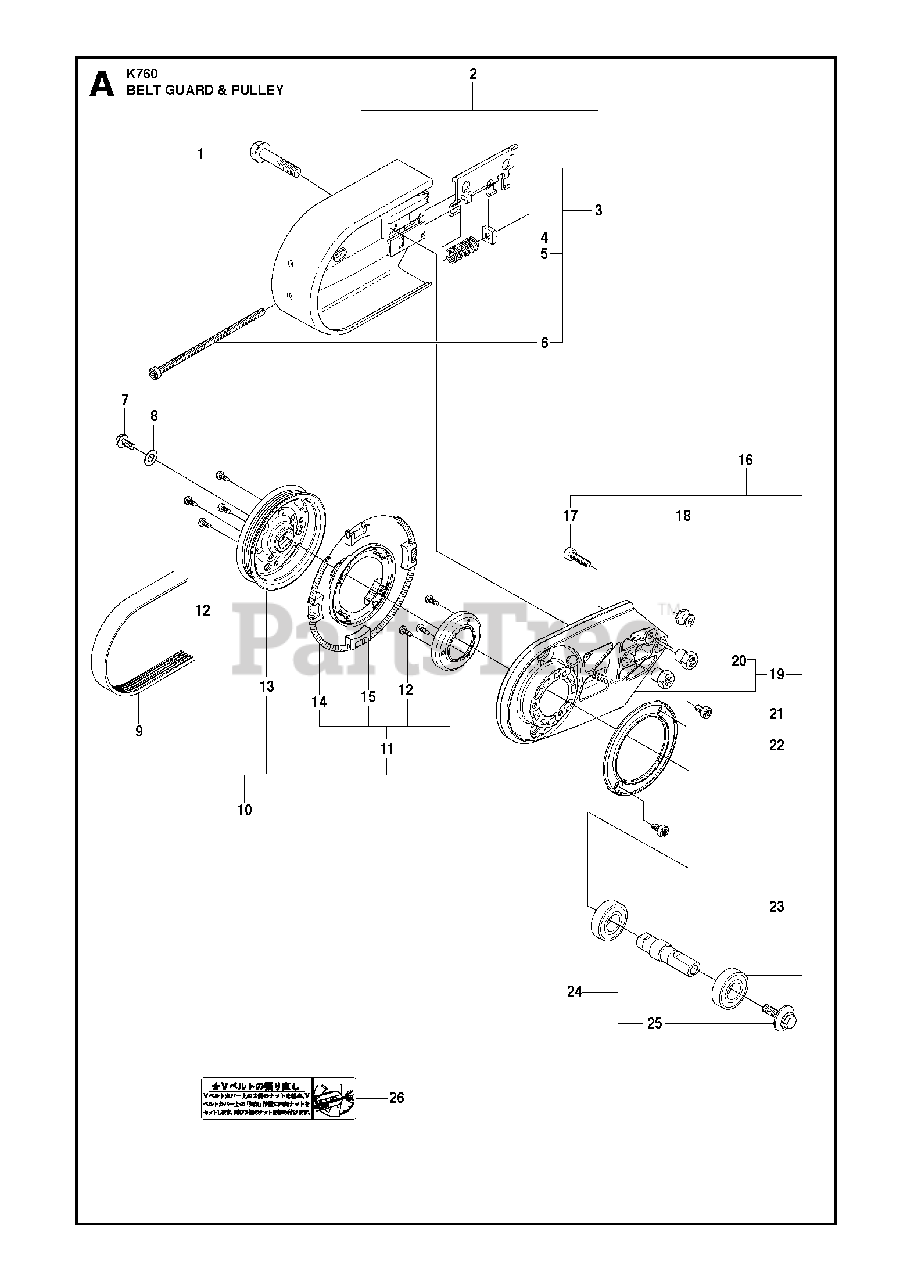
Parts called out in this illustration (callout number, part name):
2	BELT GUARDIncl. 3
3	BELT TENSIONER ASSYIncl. 4 - 6
5	COMPRESSION SPRING
6	SCREW CITXSCM
10	PULLEY ASSYIncl. 11 - 13
11	CASSETTEIncl. 12, 14 - 15
12	SCREW CCRPANT
13	PULLEY
16	BEARING HOUSINGM10, Incl. 17 - 19, 21 - 23
16	BEARING HOUSINGM8, Incl. 17-19, 21-23. UK & JP only
16	BEARING HOUSINGRescue only
17	SCREW ITXSCM
18	TORSION STOP
19	BEARING HOUSINGIncl. 20
21	SCREW ITXSCM
22	SEALING WASHER
23	BALL BEARING
24	SHAFTM8, Incl. 25
26	LABELJapan only
